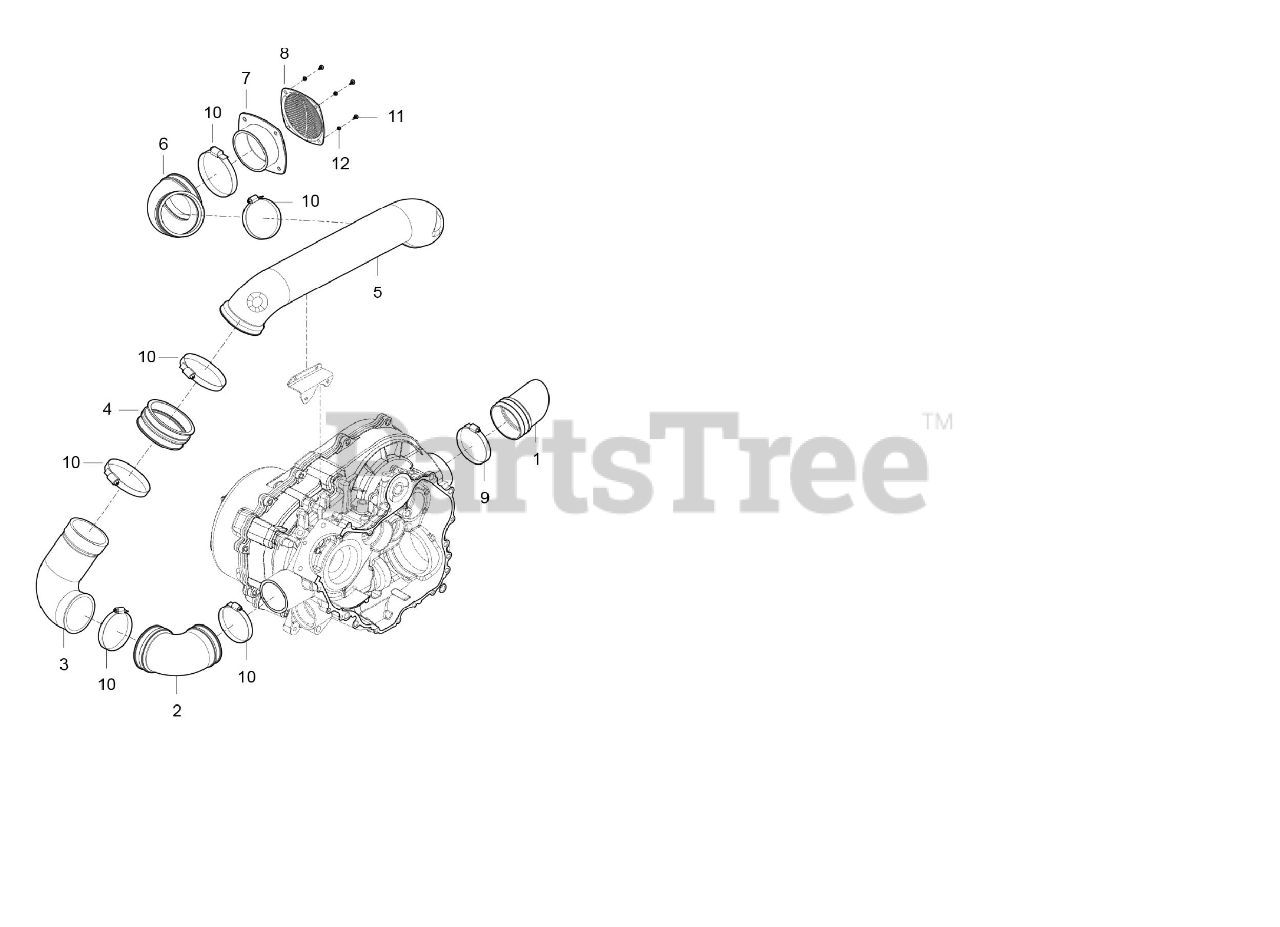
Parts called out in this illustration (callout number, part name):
1	CLUTCH AIR OUTLET SLEEVE
2	CLUTCH AIR INLET SLEEVE
3	CLUTCH AIR INLET DUCT
4	CLUTCH AIR INLET SLEEVE
5	CLUTCH AIR INLET DUCT
6	CLUTCH AIR INLET SLEEVE
7	CLUTCH AIR INLET FLANGE PLATE
9	NARROW BAND CLAMP
10	NARROW BAND CLAMP
11	Speaker Case
12	HExAGON FLANGE HEAD NUT M6
